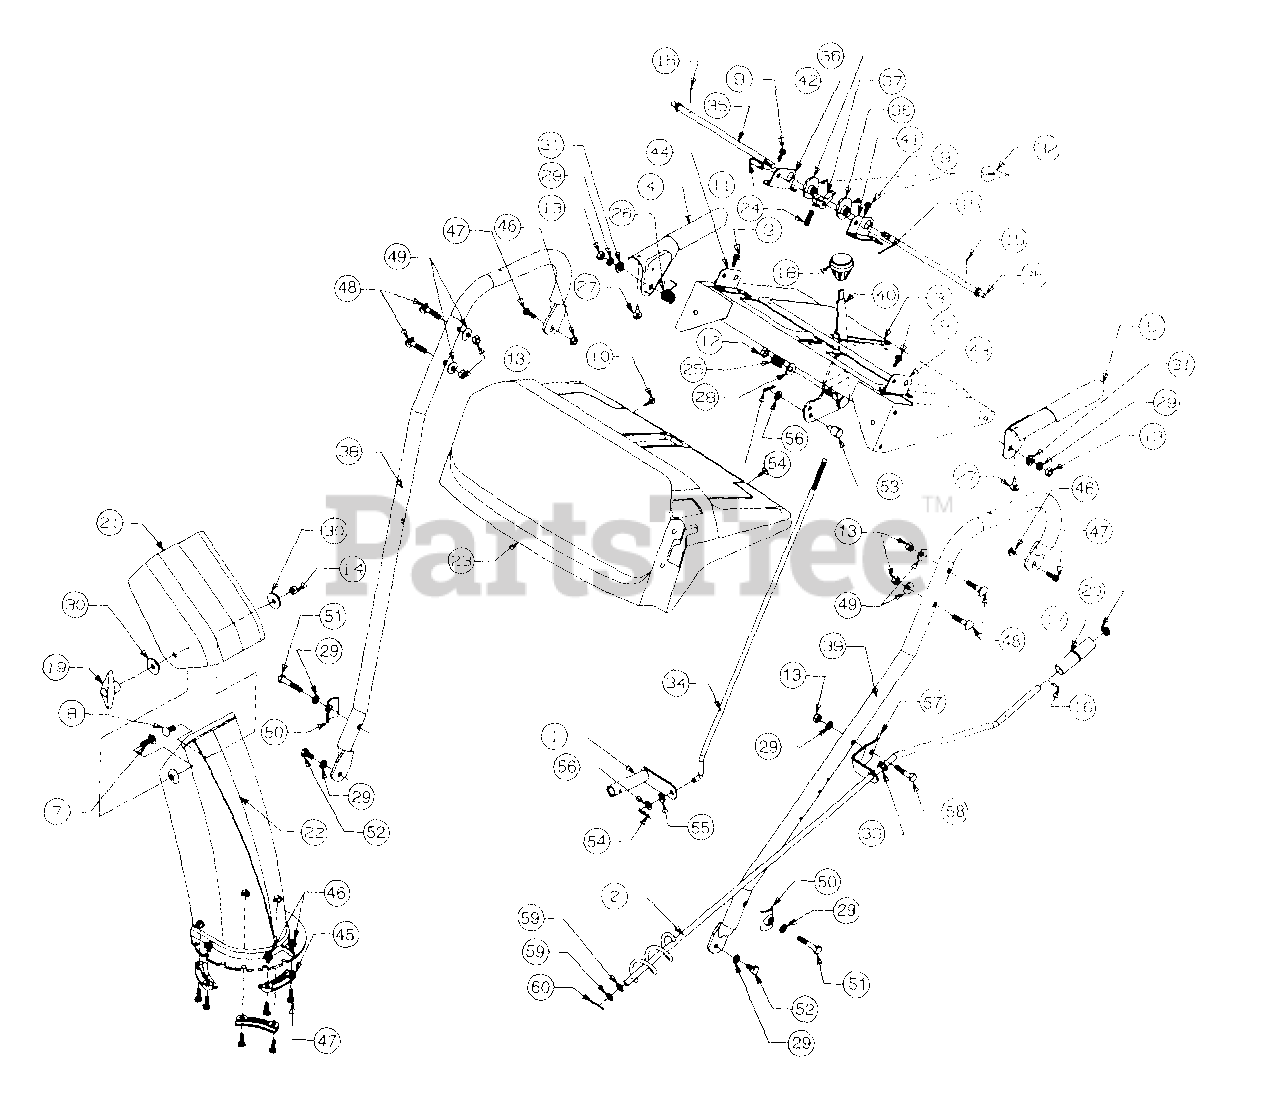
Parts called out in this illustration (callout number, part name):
1	Arm Shift
2	Crank Chute
5	Handle Grip - L.H.
7	Bolt - Carriage
8	Bolt - Carriage
9	Screw
11	Pin, Clevis
12	Nut, Lock
13	Nut, Hex
14	Nut, Lock, Hex
15	Pin, Cotter
16	Roll Pin
17	Knob, Chute Crank
18	Knob, Shift
19	Knob
20	Cap, Push
21	Chute, Upper
22	Lower Chute
23	Panel, Handle
24	Spring
25	Spring
26	Spring
27	Bumper
28	Washer - Bell
29	Washer - Lock
30	Washer
31	Washer
32	Grease
33	Bushing, Plastic
34	Rod, Shift
35	Rod, Cam
36	Cam Handle Lock
37	Pawl Handle Lock
38	Handle - R.H.
39	Handle - L.H.
40	Handle Shift
41	Bracket Handle Supt. - L.H.
42	Bracket Handle Supt. - R.H.
44	Bracket Handle Supt. - R.H.
45	Chute Flange Keeper
46	Hex L-Nut 1/4-20 Thd.
47	Hex Bolt 1/4-20 x 3/4" Lg.
48	Carr. Bolt 5/16-18 x 1.5" Lg.
49	Bell-Wash. 5/16" I.D.
50	Handle Tab
51	Hex Bolt 5/16-18 x 1.75" Lg.
52	Hex Bolt 5/16-18 x 5/8" Lg.
53	Ferrule
54	Hairpin Clip
55	Spr. Wash. 5/16" I.D.
56	Fl-Wash. 5/16" I.D.
59	Fl-Wash. 3/8" I.D.
60	Cotter Pin
